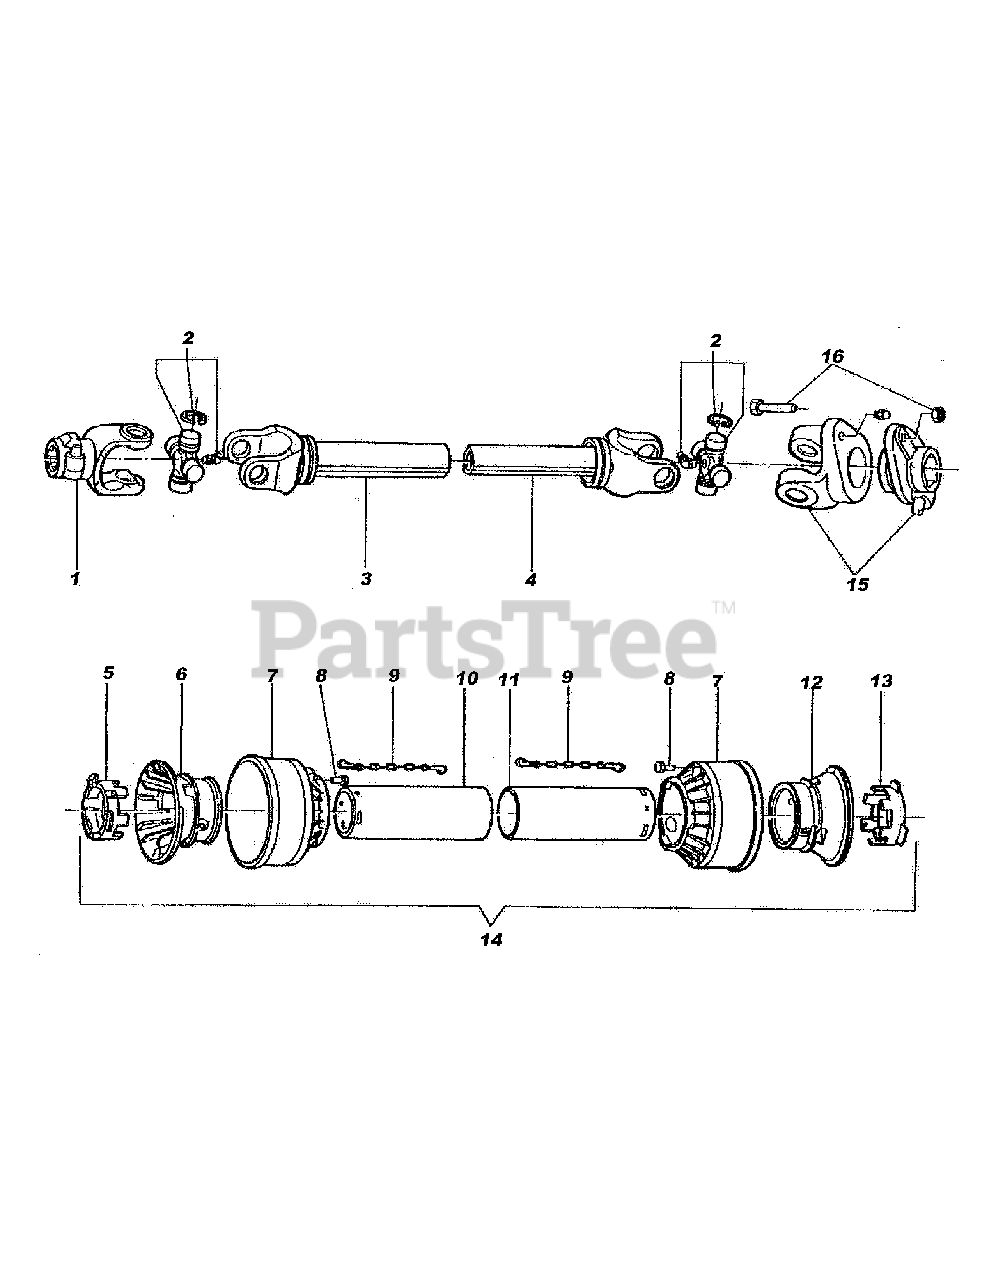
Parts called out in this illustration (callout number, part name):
1	Yoke 1 3/8''
2	Cross and Bearing
3	Outer Tube and Yoke
4	Inner Tube and Yoke
5	Tube Bearing Outer
6	Outer Tube Rigid Cone
7	Soft Cone
8	Pin for Stop Rotation
9	Chain
10	Outer Shield
11	Inner Shield
12	Inner Tube Rigid Cone
13	Tube Bearing Inner
14	Shield Complete
15	Yoke Shearbolt
16	Shearbolt and Nut
